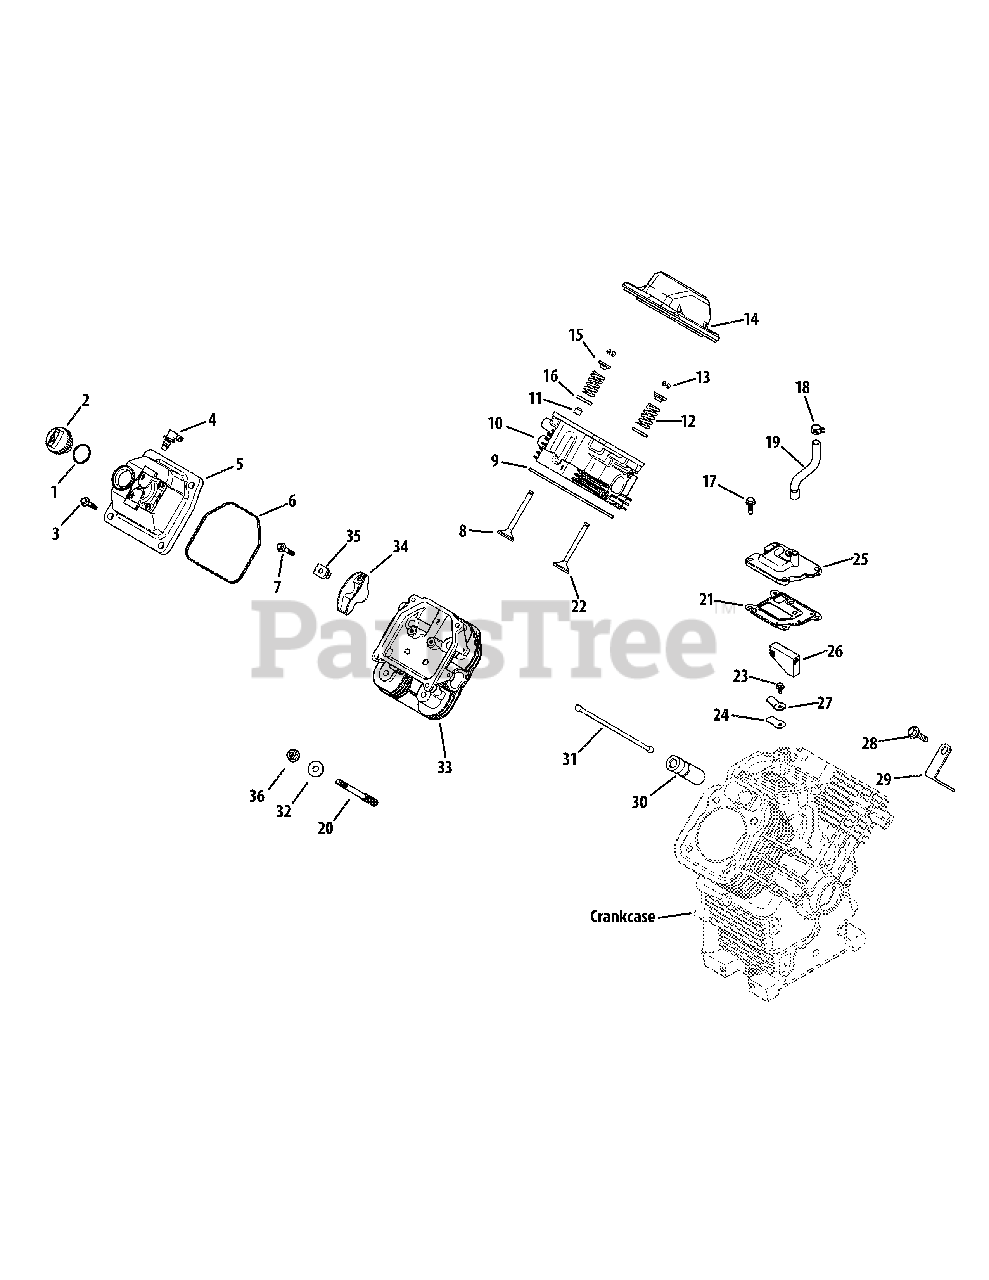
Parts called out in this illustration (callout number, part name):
2	Oil Fill Cap Assembly
3	Flange Screw, M6 x 1.0 x 30
4	90 Degree Fitting Kit
5	Valve Cover-Fuel Pump Kit
6	Vlave Cover O-Ring
7	Flange Screw, M6 x 1.0 x 34
8	Exhaust Valve (Std)
8	Exhaust Valve (.25)
9	Cylinder Head Gasket Kit (C17-22)
10	#1 Cylinder Head Assembly Kit
11	Valve Stem Seal
12	Valve Spring
13	Retainer Kit
14	Valve Cover-Plain Kit
15	Valve Spring Cap
16	Spring Retainer
17	Thread Forming Screw
18	Spring Hose Clamp
19	Breather Hose
20	Stud, M8 x 1.25
21	Breather Gasket
22	Intake Valve (Std)
22	Intake Valve (.25)
23	Flange Screw, M5 x .8 x 10
24	Breather Reed
25	Breather Assembly Kit
26	Breather Filter
27	Reed Retainer
28	Thread Forming Screw
30	Hydraulic Valve Lifter
32	Flat Washer, 8.6MM
33	#2 Cylinder Head Assembly Kit
34	Valve Train Kit
35	Rocker Arm Pivot
36	Nut, Flange, M8 x 1.25
